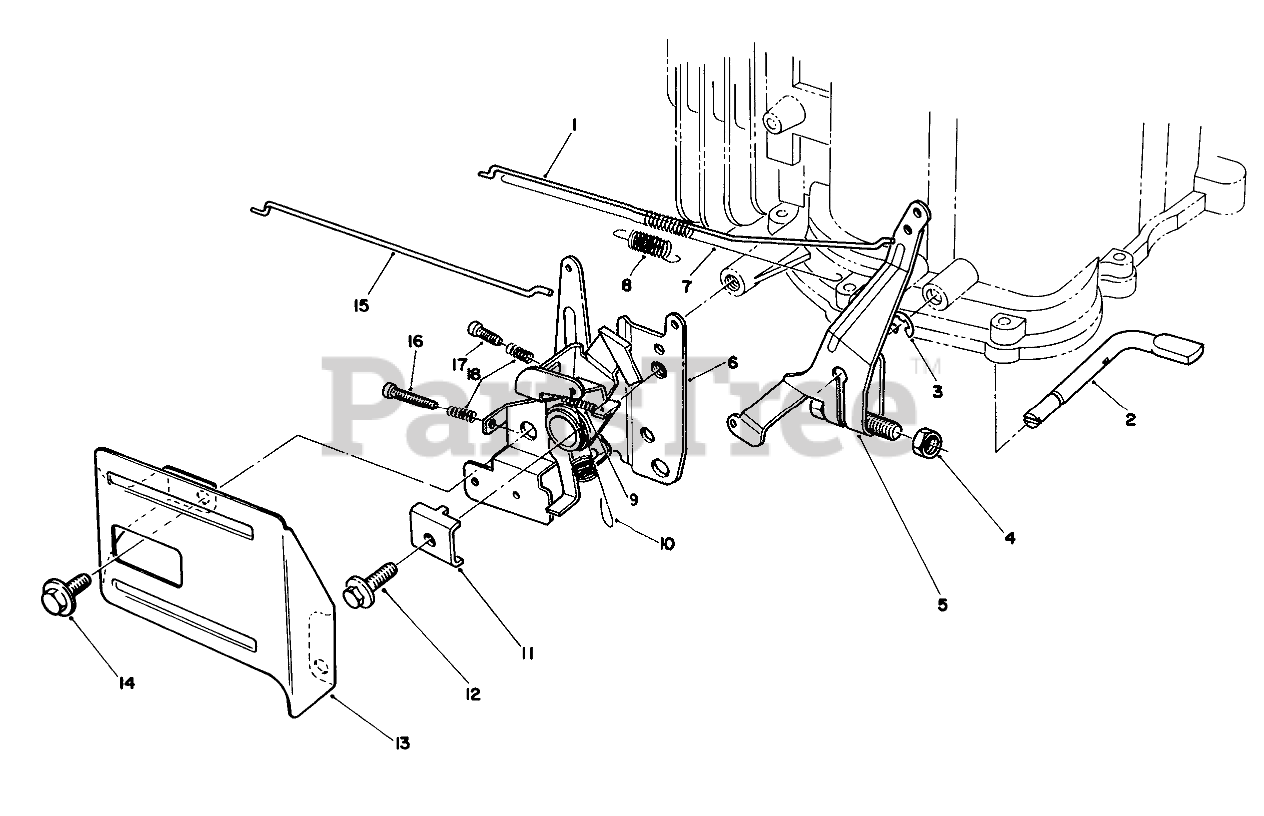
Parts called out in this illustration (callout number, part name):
1	Rod-Carburetor
2	SHAFT
3	E-RING
4	Nut
5	ARM ASM
6	THROTTLE
7	SPRING
8	SPRING
9	SPRING
10	SPRING
11	CLAMP-CABLE
13	THROTTLE GUARD
15	Rod-Choke
16	SCREW
17	SCREW
18	SPRING
